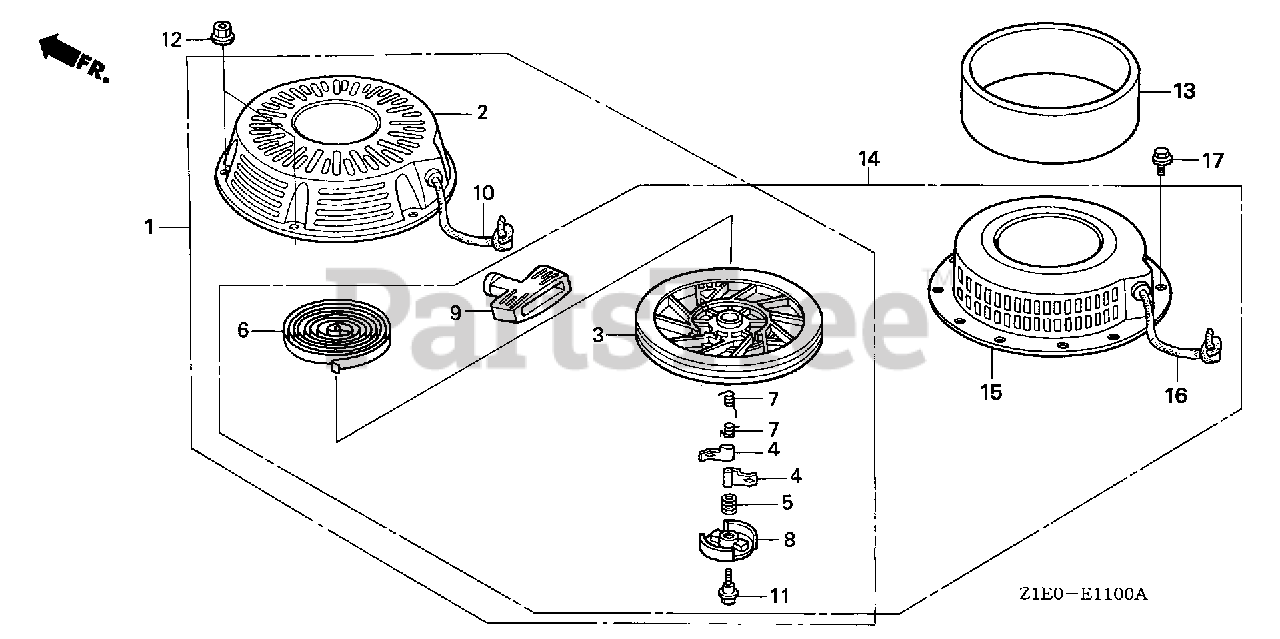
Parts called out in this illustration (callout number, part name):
1	STARTER ASSY., RECOIL *NH1* (BLACK)
1	STARTER ASSY., RECOIL *R280* (POWER RED)
2	CASE, RECOIL STARTER *NH1* (BLACK)
2	CASE, RECOIL STARTER *R280* (POWER RED)
3	PULLEY, RECOIL STARTER
4	RATCHET, STARTER
5	SPRING, FRICTION
6	SPRING, STARTER RETURN
7	SPRING, RATCHET
8	RETAINER, SPRING
9	GRIP, STARTER
10	ROPE, RECOIL STARTER (#6X64") (N/A: USE P/N 08560-ZG921-11)
11	SCREW, CENTER
12	NUT, FLANGE (6MM)
